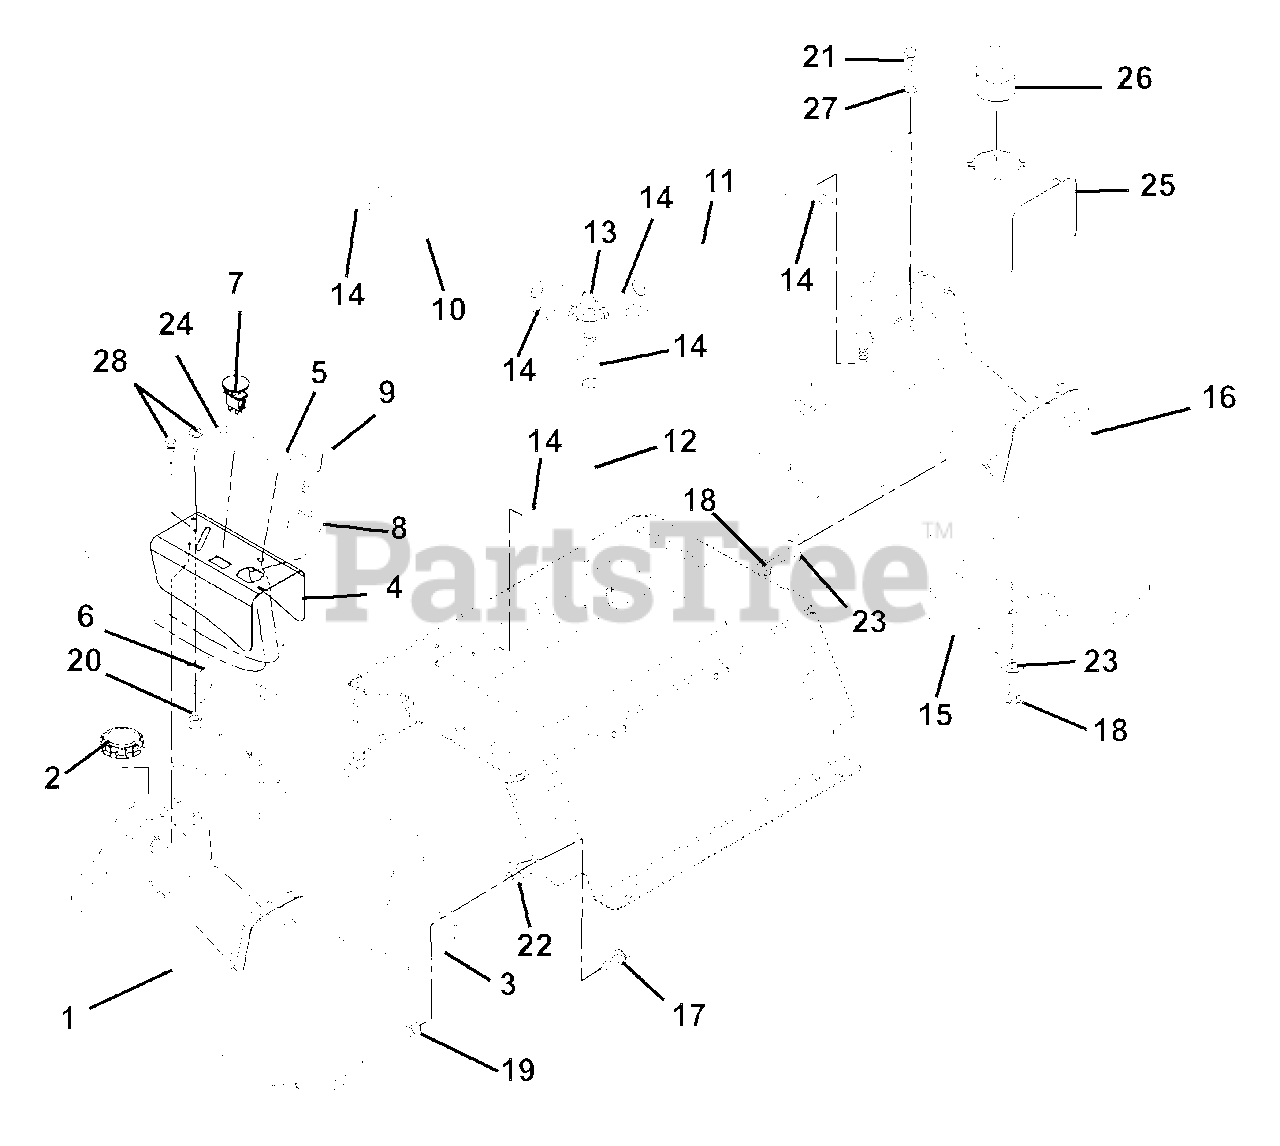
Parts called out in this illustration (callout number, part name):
1	FUEL TANK, RH
2	FUEL CAP
3	SEAT PLATE, RH
4	RH CONSOLE
5	HOLE PLUG, PLASTIC .44 HOLE
6	THROTTLE CABLE
7	SWITCH, CLUTCH
8	KEY SWITCH
9	KEY -W/CAP
10	GAS LINE-BULK 1/4" I.D.
11	GAS LINE-BULK 1/4" I.D.
12	GAS LINE-BULK 1/4" I.D.
13	VALVE, FUEL
14	CLAMP-HOSE WIRE .490/.510X.116
15	SEAT PLATE, LH
16	FUEL TANK, LH
17	@BLT-RDHDSQNK .38-16X1.00 G5YZ
18	BLT-SERHFWH .312-18X.50 YWZC
19	@NUT-LK-NYL-FLG .38-16 YWZC
20	@NUT-LK-NYL 10-24 W/INSRT YWZC
21	SCR-MCH 10-24X3/8 SL HEX YWZC
22	RETAINER, .38 PUSH-ON
23	WSHR-FL-STL .347X1.254X.048YWZ
24	SHIM,PTO SW (DELTA #972301)
25	LH CONSOLE
26	CUPHOLDER
27	WASHER, FENDER 3/16X3/4 YWZC
28	@SCR-MCH 10-24X.50 HWH YWZC
